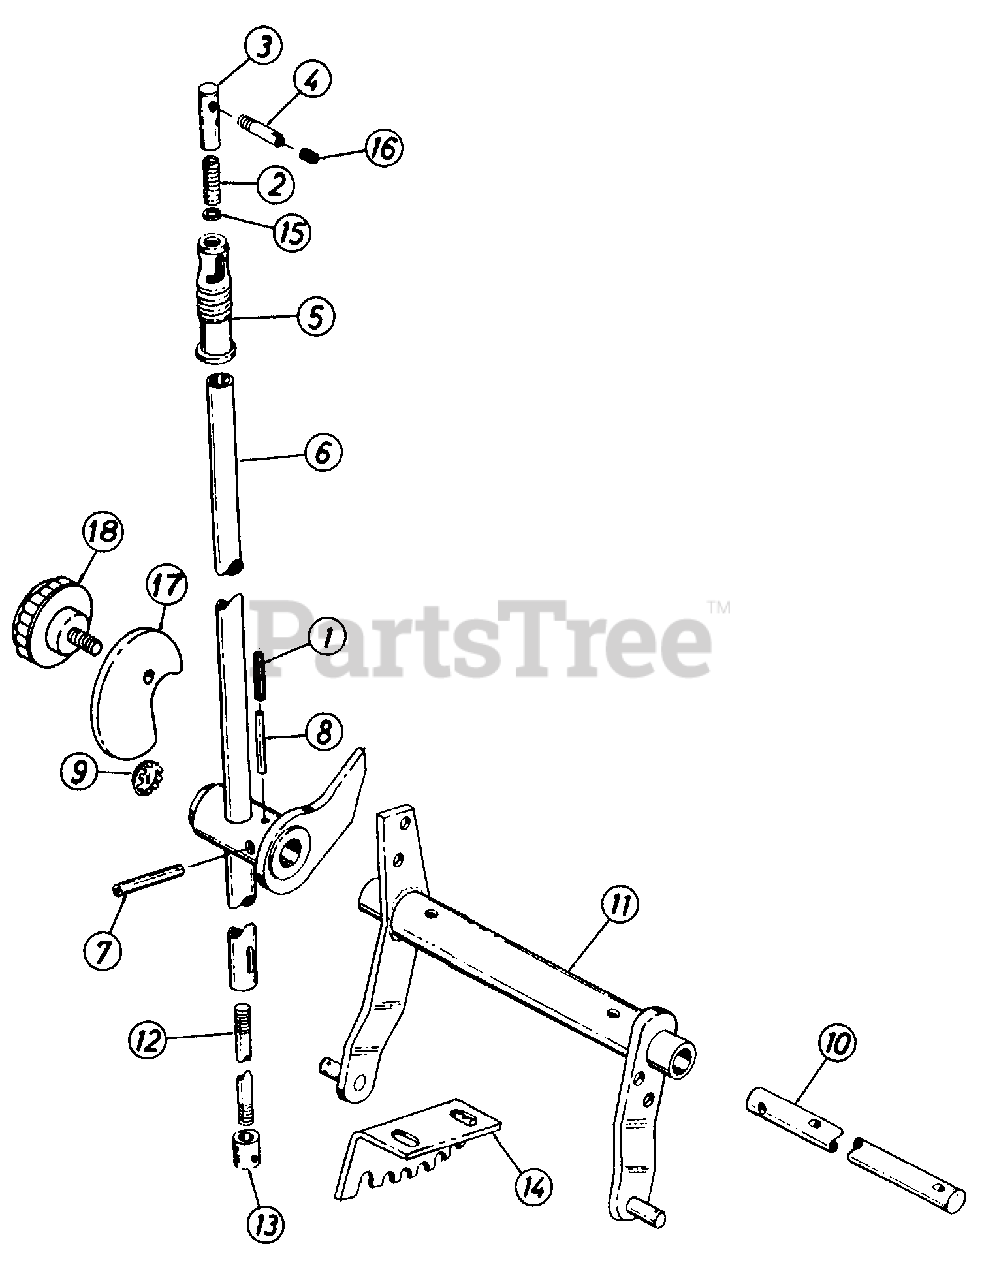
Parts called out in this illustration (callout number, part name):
1	Pointer, Lift
2	Spring, Lift Handle
3	Pin, Release
4	Pin, Float
5	Grip, Lift Handle
6	Lever Assy, Lift
7	Pin, 3/8 X 2 Hvy Pln Cld Spr
8	Pin, 3/16 X 3 Med Pln Cld Spr
9	Plug, 1.0 Hole Dia Crb Button
10	Rockshaft
11	Arm Assy, Rockshaft
12	Stud, Handle
13	Rod, Handle Release
16	Cap, Float Lock Pin
18	Knob, Torque
